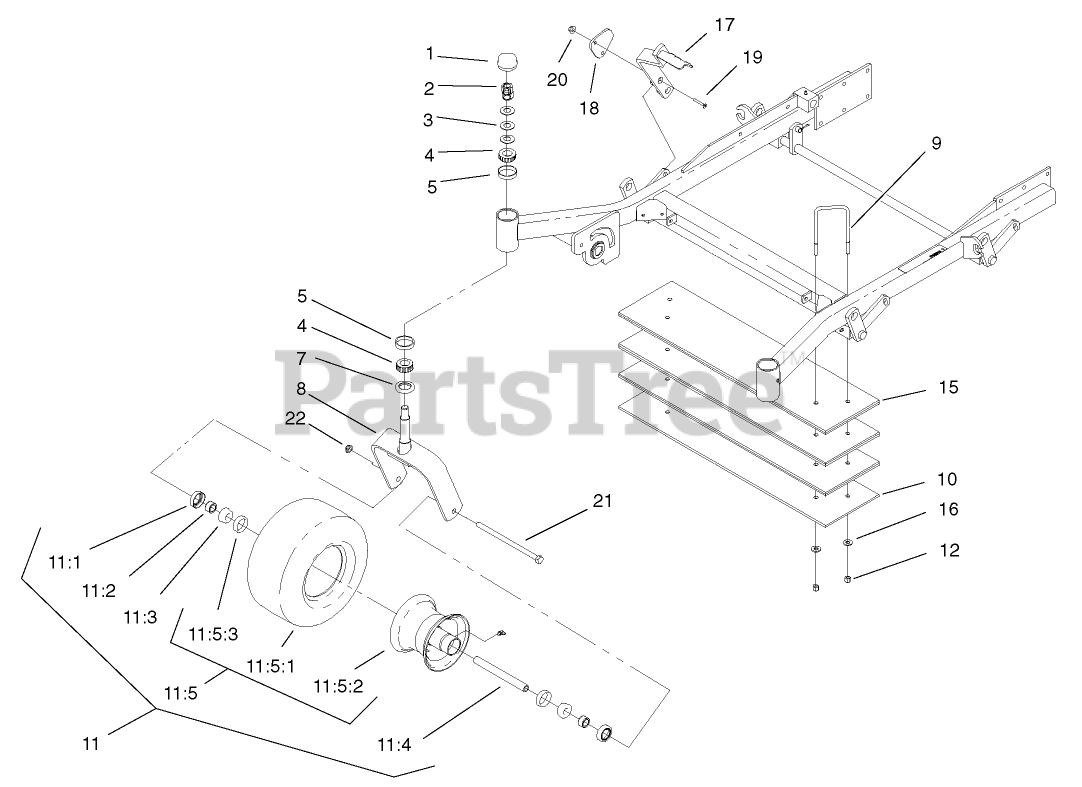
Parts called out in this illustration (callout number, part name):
1	CAP-GREASE
2	NUT-LOCK, NI
3	WASHER-BELLVILLE
4	BEARING-CONE, TAPERED
5	BEARING-CUP, TAPERED
7	SEAL-GREASE
8	CASTER-FORK
9	U-BOLT
10	BAR-WEIGHT
11	CASTER WHEEL ASM
11:1	SEAL-BEARING
11:2	SPACER-BEARING
11:3	BEARING-CONE, TAPER
11:4	SPACER-CASTER, FRONT
11:5	WHEEL AND TIRE ASM
11:5:3	BEARING-CUP
12	NUT-LOCK, NI
15	WEIGHT BAR ASM
16	WASHER-FLAT
17	LEVER-LIFT, DECK
19	SCREW
20	NUT-HF
21	Screw-HH
22	NUT-LOCK, NI
